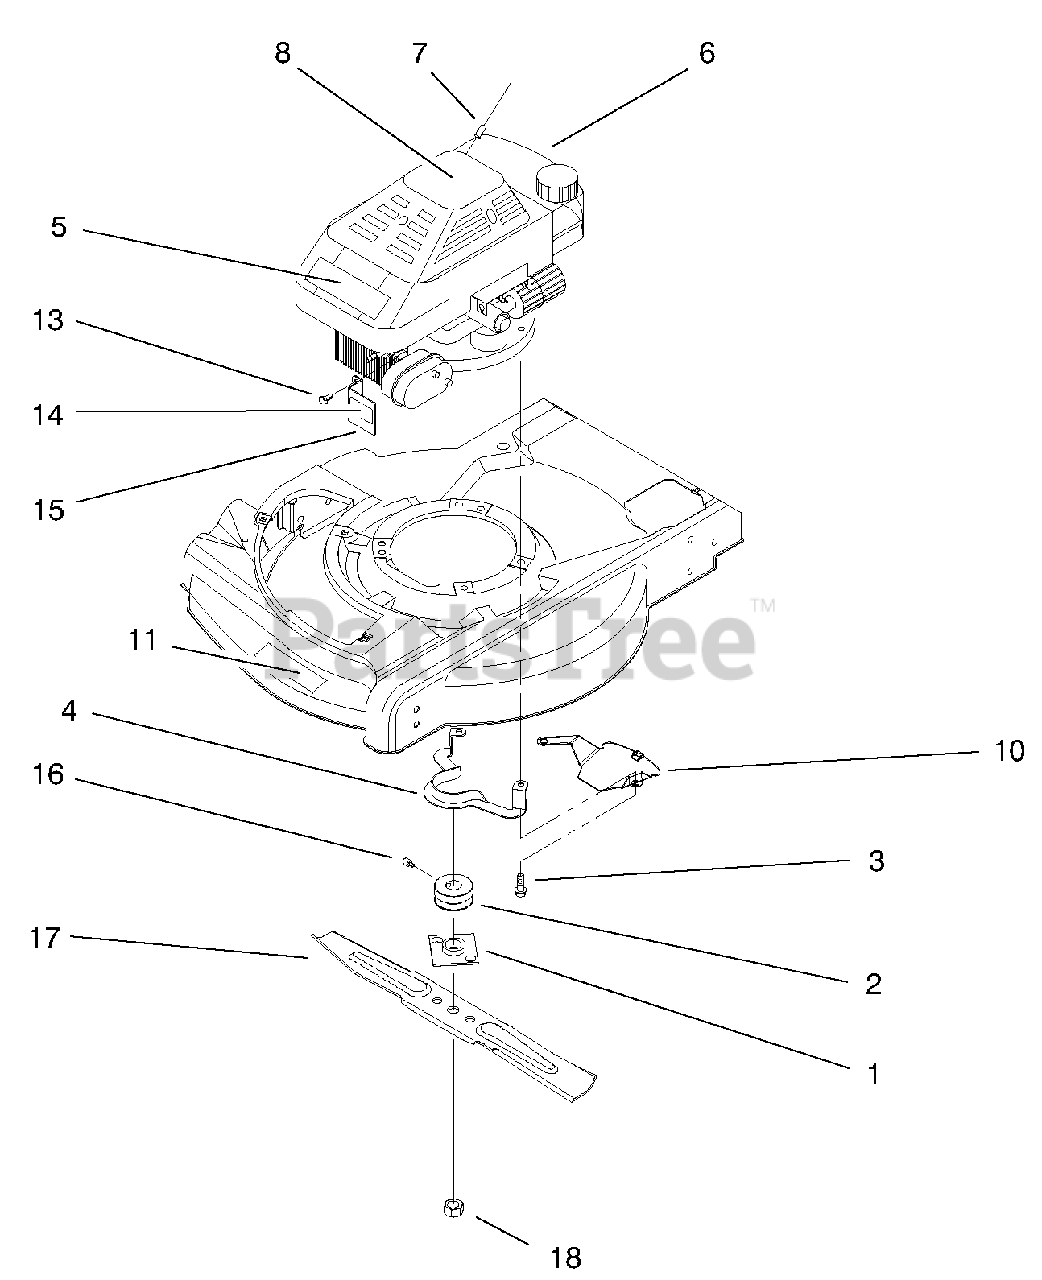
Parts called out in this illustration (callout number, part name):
1	ASM-Plate & Collar
2	Pulley-Engine
3	Screw-Engine Mount
4	Guide-Belt
5	Applique
6	ASM-Engine
7	Rope-Stop
8	Decal-Shroud Top
10	Shield-Grass
11	Decal-Deck
14	Decal-Hot Surface
15	Guard-Muffler
16	Screw-Set
17	Blade-21" Whirl
18	Nut-Blade
